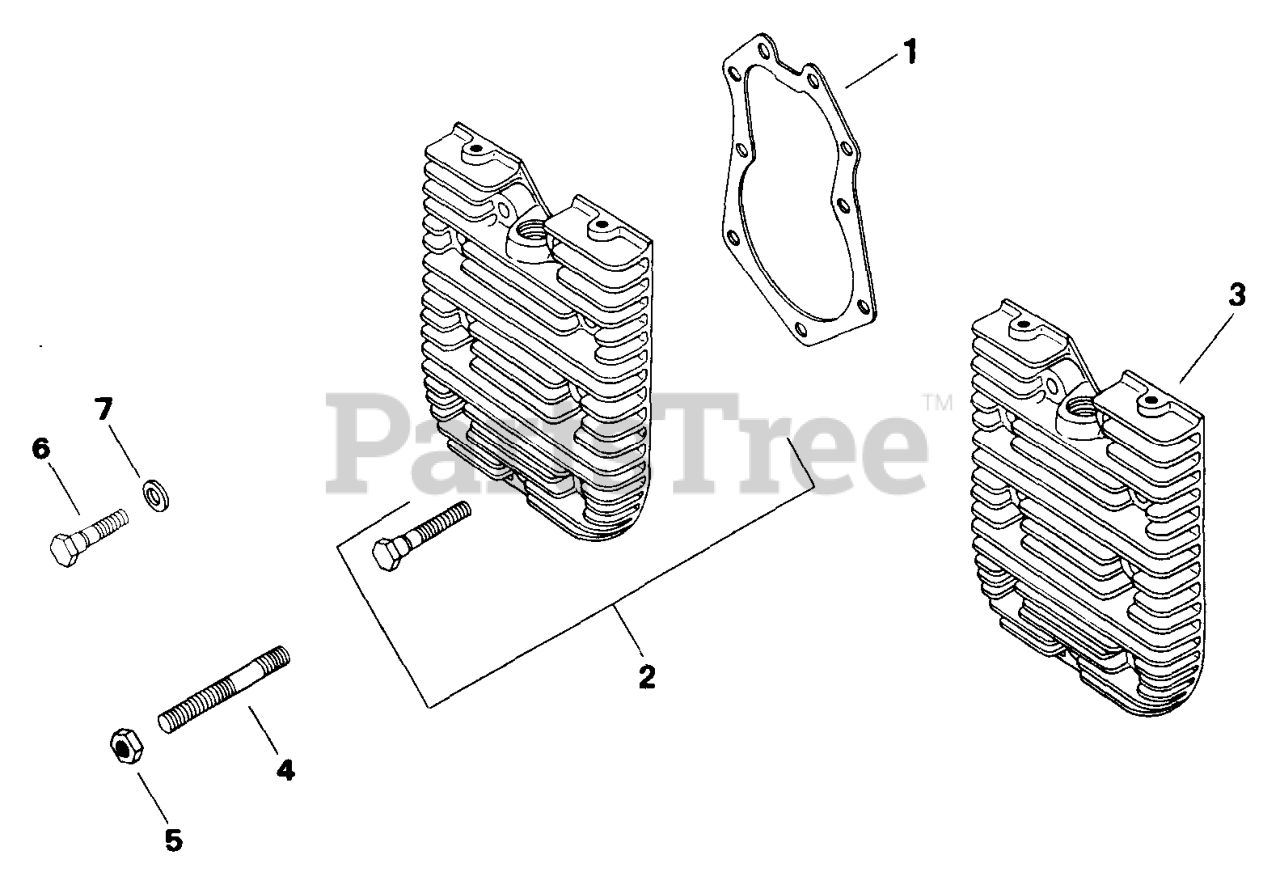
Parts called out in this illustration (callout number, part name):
1	Gasket, Cylinder Head
2	Kit, Cylinder Head
3	Head, Cylinder
4	Stud 5/16-18x2"
5	Nut, Hex. 5/16-18
6	Screw, Hex. Hd. 5/16-18x1-1/2"
6	Screw, Hex. Mach. 5/16-18x2"
7	Washer, Plain 5/16"
